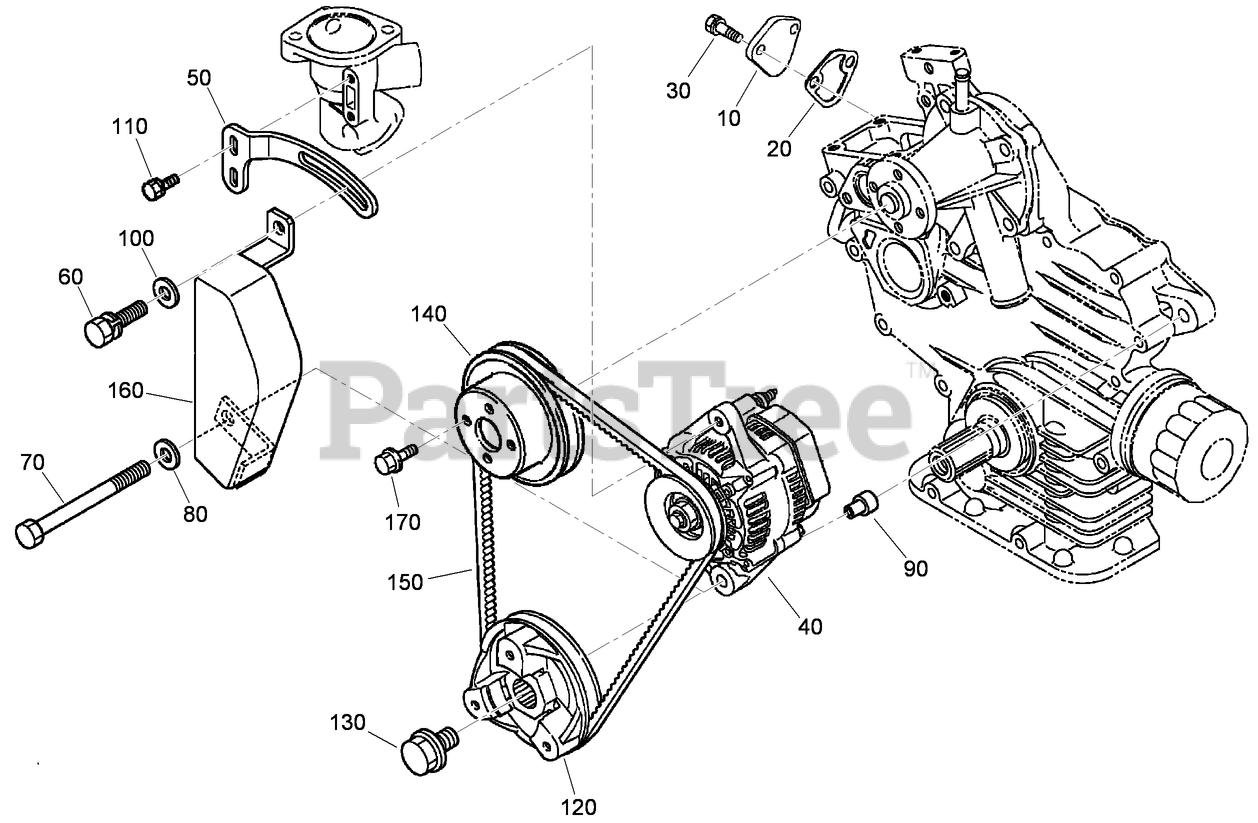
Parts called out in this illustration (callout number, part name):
10	COVER
20	GASKET-PUMP, FUEL
40	ALTERNATOR ASM
50	STAY-ALTERNATOR
80	WASHER-PLAIN
90	COLLAR
100	WASHER-PLAIN
120	PULLEY-DRIVE, FAN
140	PULLEY-FAN
170	BOLT-FLANGE
